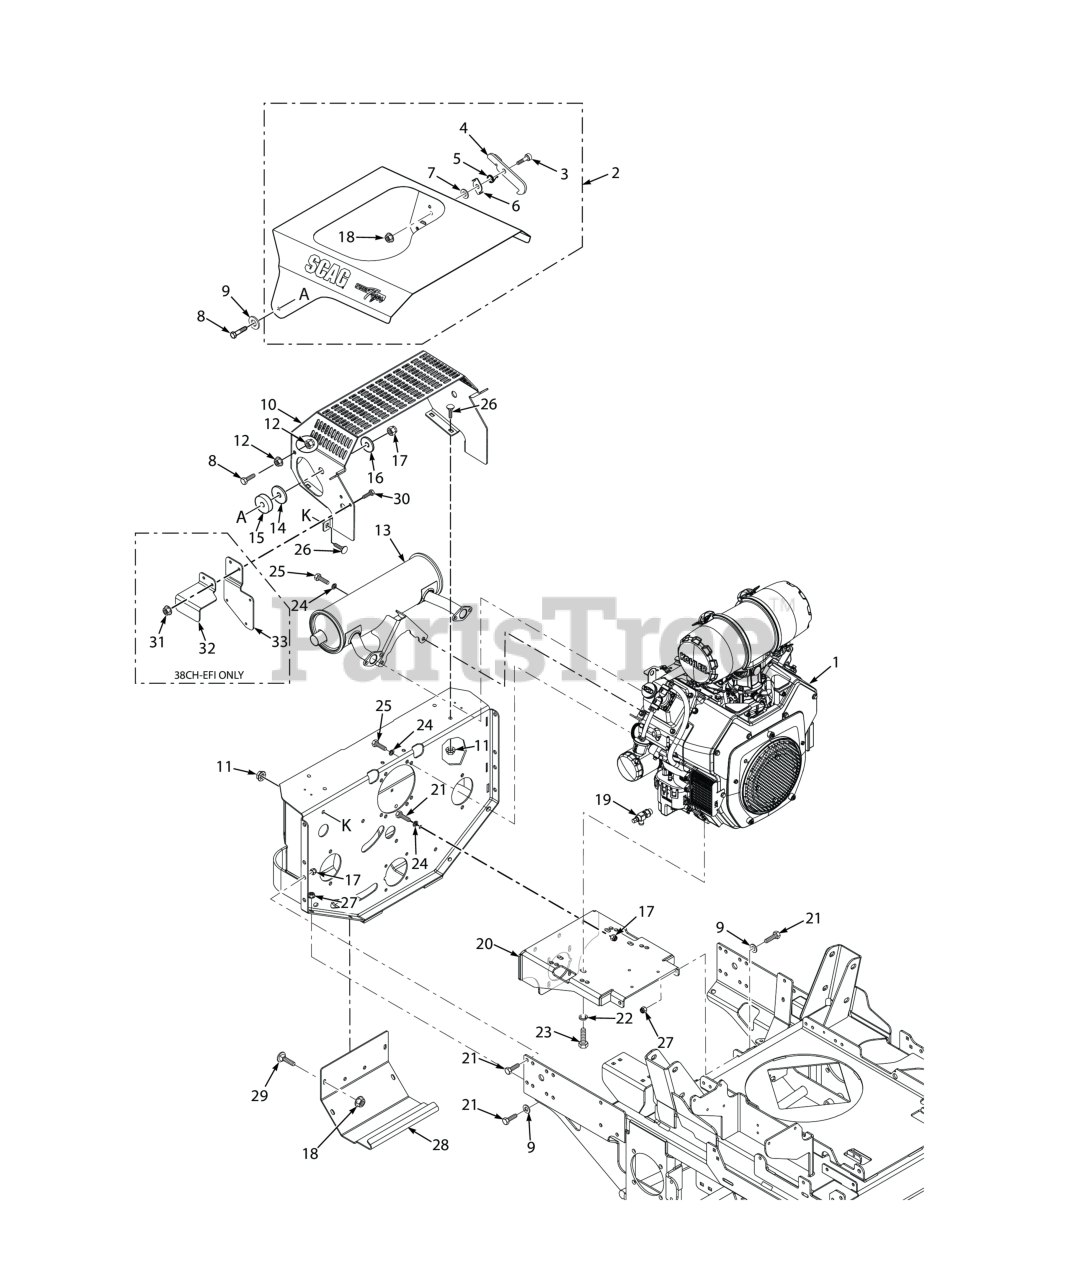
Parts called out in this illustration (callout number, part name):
1	Engine, 40BV-EFI - Briggs & Stratton
2	Hood Assy., STTII (37BV-EFI)
3	Bolt, Shoulder 5/16-18 x 1/2"
4	Latch, Hood
5	Spring, Hood Latch
6	Lock, Hood Latch
7	Flatwasher, 3/8 (.406 x .812 x .065)
8	Bolt, Hex Head 3/8-16 x 1-3/4" (Kohler EFI)
9	Flatwasher, 3/8" Special (.391 x .938 x .105)
10	Guard, Muffler
11	Nut, Flange Head Elastic Stop 5/16-18
12	NUT, 3/8-16 SERRATED FLANGE HEX HEAD
13	Muffler, 37BV-EFI & 40BV-EFI - Briggs & Stratton
14	Disc, Anti-Friction
15	Spacer, Hood
16	Flatwasher, 3/8-.406 x 1-1-1/2 x 7 Gauge
17	HEX NUT, ELASTIC STOP LOCK, 3/8-16
18	Nut, Serrated Flange 5/16-18 (Right Front Engine Mounting, Briggs and Kohler Only)
19	Oil Drain, 35BV & 37BV-EFI - Briggs & Stratton
20	Plate Weldment, Engine Mounting
21	Bolt, Hex Head, 3/8-16 x 1 Gr. 5
22	Lockwasher, 3/8" Spring, Kawasaki FX / FT & FT-EFI / B&S 32BV
23	Bolt, Hex Head 5/16-18 x 2-1/2" (x3) (35BV & 37BV-EFI)
24	Lockwasher, 3/8" Spring, Kawasaki FX / FT & FT-EFI / B&S 32BV
25	Bolt, Hex Head, 3/8-16 x 1 Gr. 5
26	Bolt, 5/16-18 x .75 RHSN Carriage
27	Nut, Flange Elastic Stop Nut, 3/8-16
28	Cover, Rear
29	Bolt, 5/16-18 x .75 RHSN Carriage
30	BOLT, SERRATED FLANGE HEX HEAD 5/16-18 X 3/4"
31	Nut, Serrated Flange 5/16-18 (Right Front Engine Mounting, Briggs and Kohler Only)
32	Guard, Fuel Pump
33	Bracket, Fuel Pump
